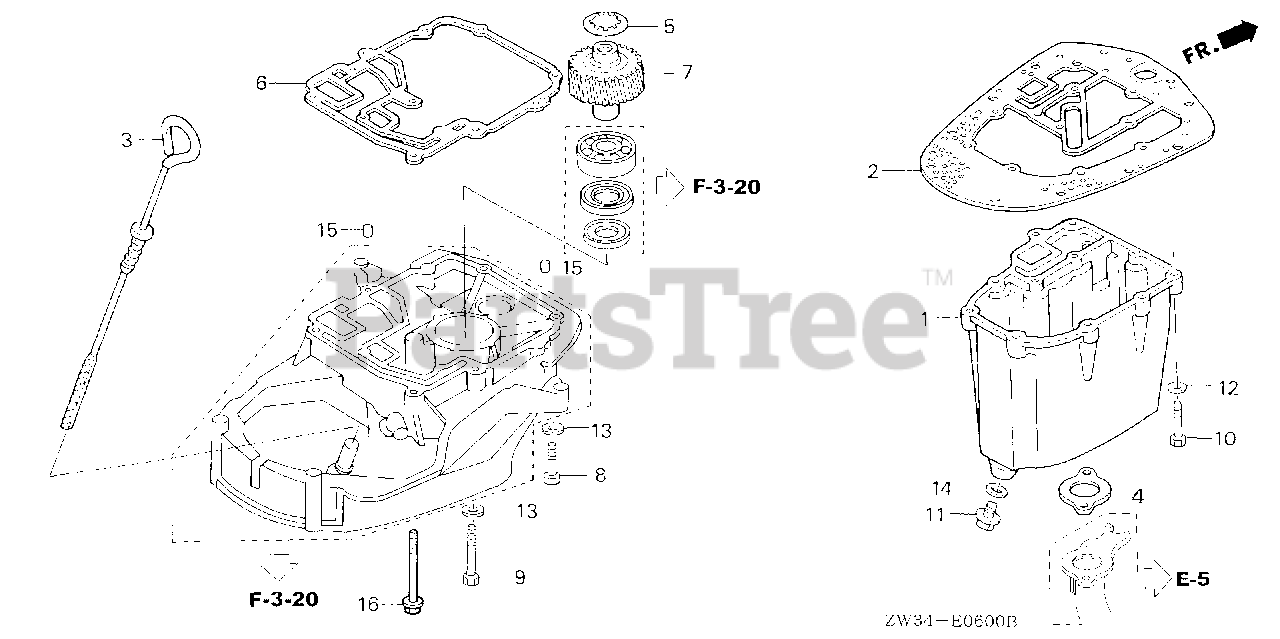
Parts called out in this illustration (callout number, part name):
1	PAN, OIL *TGRAY* (GRAY)
2	GASKET, OIL PAN
3	DIPSTICK, OIL
4	GASKET, EX. PIPE
5	SPRING, THRUST
6	GASKET, PRIMARY GEAR CASE
7	GEAR, PRIMARY DRIVEN (33T)
8	BOLT, HEX. (8X35)
9	BOLT, HEX. (8X55)
10	BOLT, HEX. (6X25)
11	BOLT, DRAIN PLUG
12	WASHER, PLAIN (6MM)
13	WASHER, PLAIN (8MM)
14	WASHER, DRAIN PLUG (12MM)
15	PIN, DOWEL (6X10)
16	BOLT, FLANGE (8X75)
